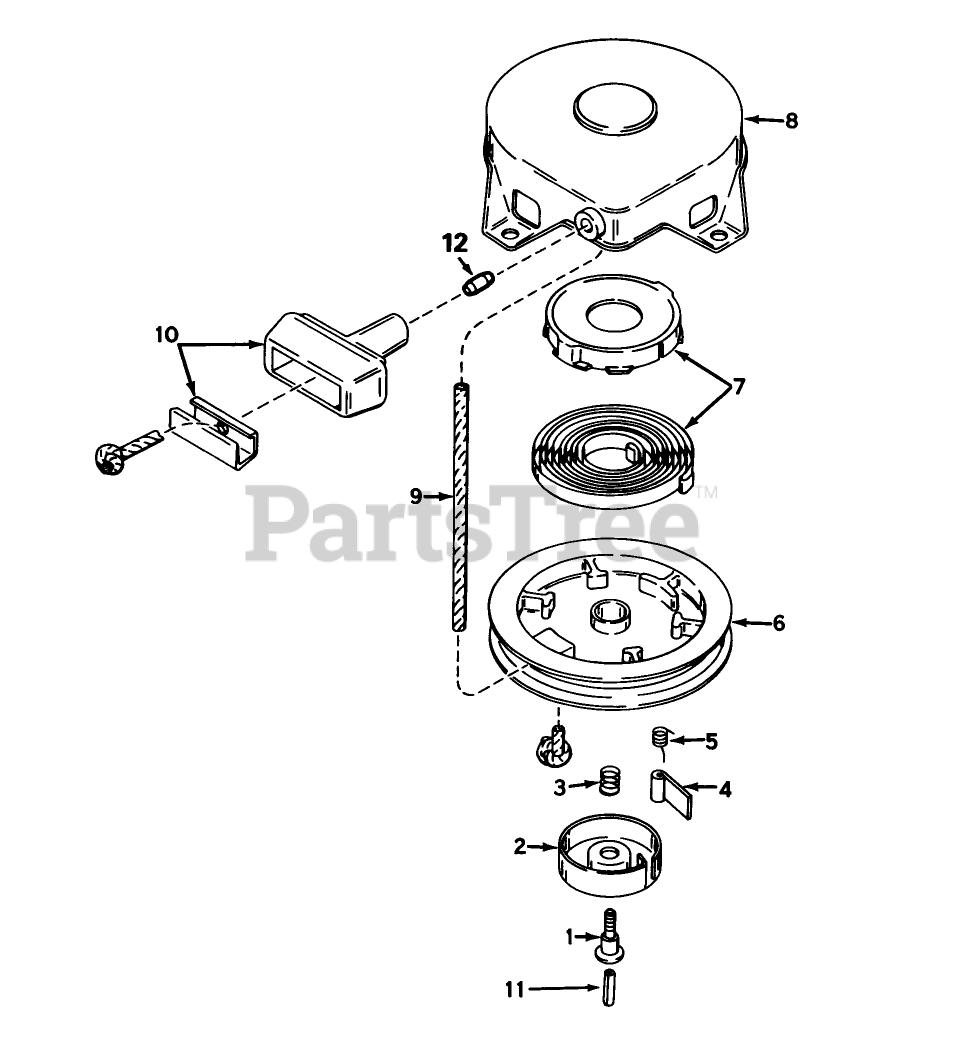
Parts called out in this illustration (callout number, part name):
1	Screw
2	Retainer
3	Spring-Brake
4	Dog-Starter
5	Spring-Dog
6	Pulley
7	Spring Keeper Assy
8	Housing Assy., Starter (Incl. Ref. #1)
9	Rope-Starter (98 cut to length)
10	Assy., Starter
11	Centering
12	Retainer-Starter Rope
